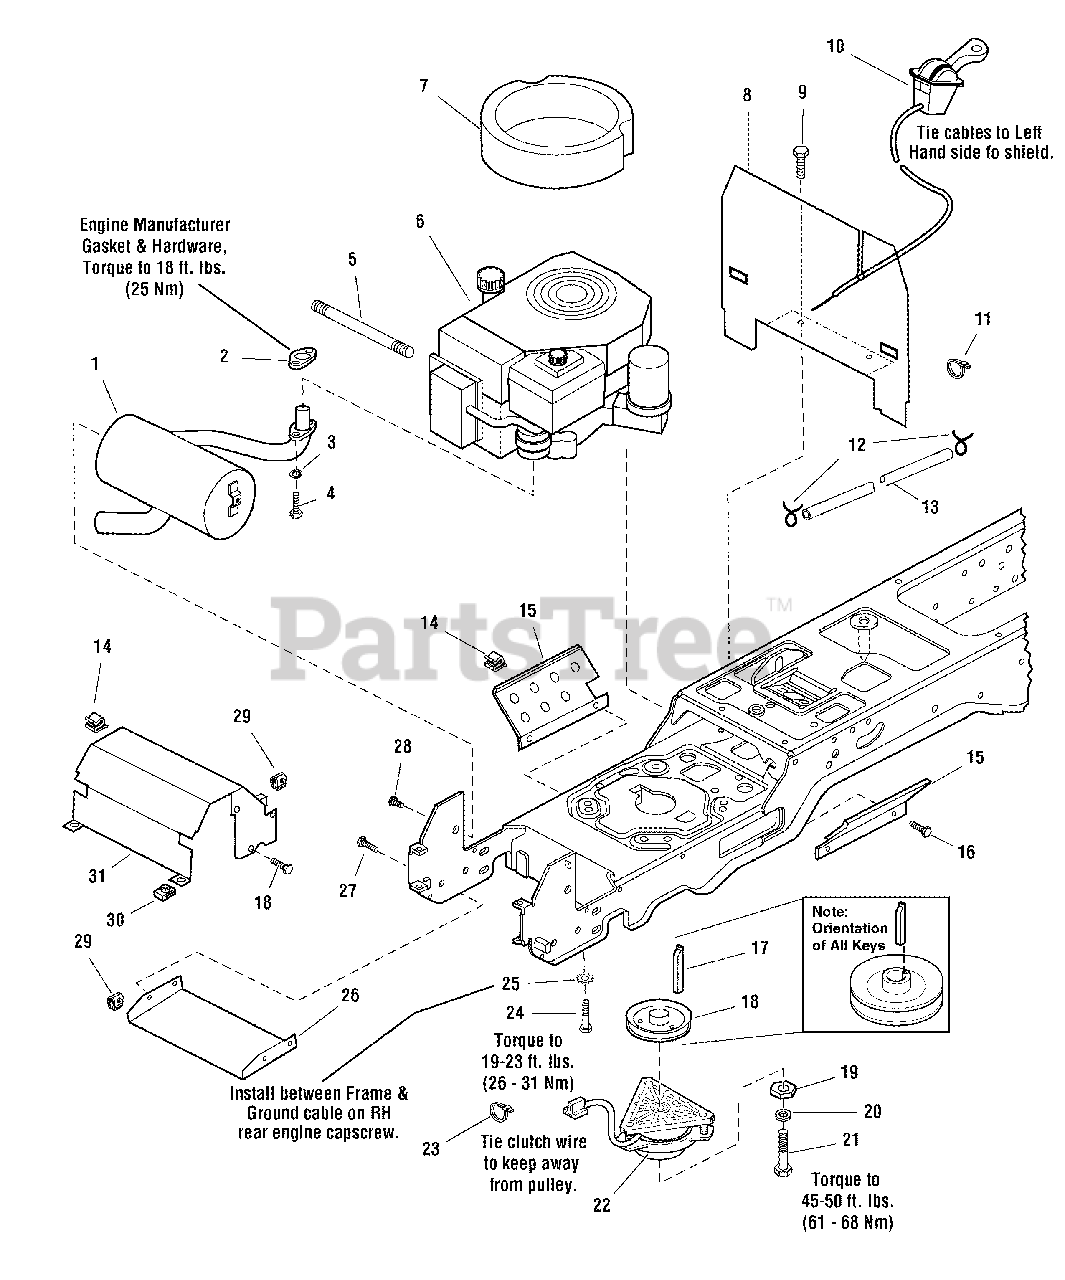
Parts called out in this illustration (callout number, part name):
2	GASKET
5	HOSE, Oil Drain
7	SEAL, Circle
9	CAPSCREW, Hex Head Taptite, 1/4-20 x 1/2
10	CONTROL, Throttle Single 39" Long w/Knobs
11	TIE, Self Locking
12	CLAMP, Hose Type E
13	HOSE, 59" Long
14	CLIP, Wire
16	SCREW, Hex Head Taptite, 1/4-20 x 3/8
18	PULLEY & HUB ASSEMBLY, 4-1/2 OD
19	WASHER, Hex
20	LOCKWASHER, 7/16
21	CAPSCREW, Hex Head, 7/16-20 x 2-3/4
22	CLUTCH, Electric, OGURA
24	CAPSCREW, Hex Head Taptite, 3/8-16 x 1-1/2
25	LOCKWASHER, External Tooth, 3/8
26	SHIELD, Muffler Bottom
27	CAPSCREW, Hex Head Flange Lock, 1/4-20 x 5/8
28	CAPSCREW, Hex Head Taptite, 5/16-18 x 1/2
29	NUT, Speed, 1/4-20
30	NUT, Speed, 5/16-18
31	DUCT, Muffler Top
32	DUCT, Muffler Extension
